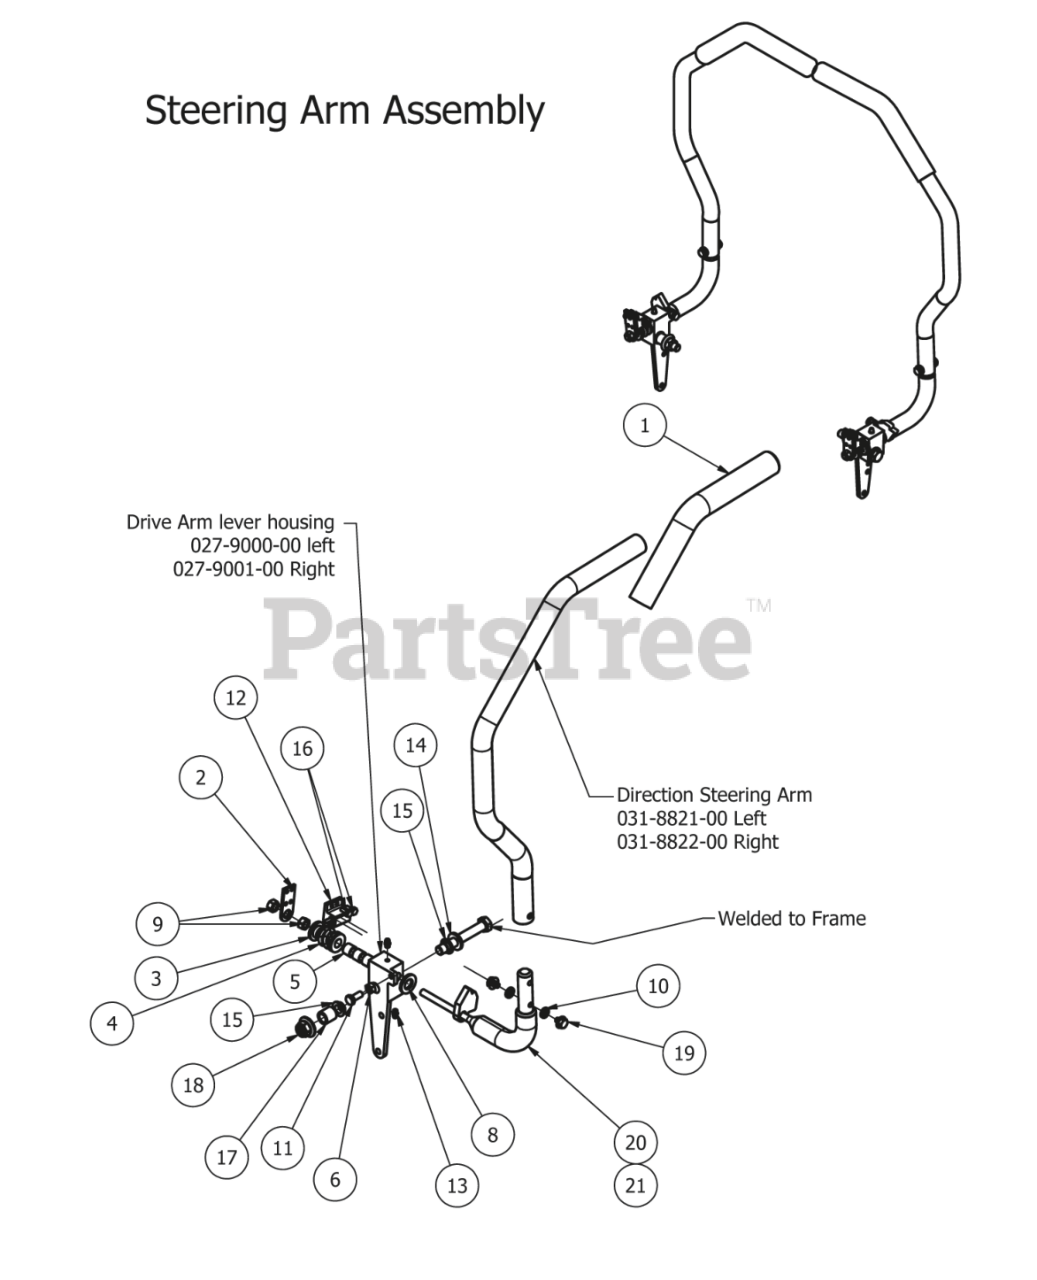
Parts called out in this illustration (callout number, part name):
1	Rubber Grip
2	MZ Switch Bracket
3	.515 ID Nylon Shoulder Washer
4	Drive Lever Spring
5	.507 ID Nylon Bushing
7	1/2 x 3 1/2 Flange Bolt Grade 8
8	.635 ID Plastic Washer
9	3/8" Fine Threaded Jam Nut
10	5/16" Lock Washer
11	5/16" x 3/4" Hex Bolt
12	Safety Switch
13	1/4" Drive in Grease Fitting
14	.505x1x .125 Oil Impregnated washer
15	Bushing For 2012 Drive arm
16	12-24x 1/2 HWH Bolt
17	3/4 OD x 1/2 ID x 3\4 Length
18	1/2-13 Nylon Flange Nut-Orange
19	5/16-18 1/2 HWH Bolt-Steering
20	Steering Arm Elbow (Right)
21	Steering Arm Elbow (Left)
